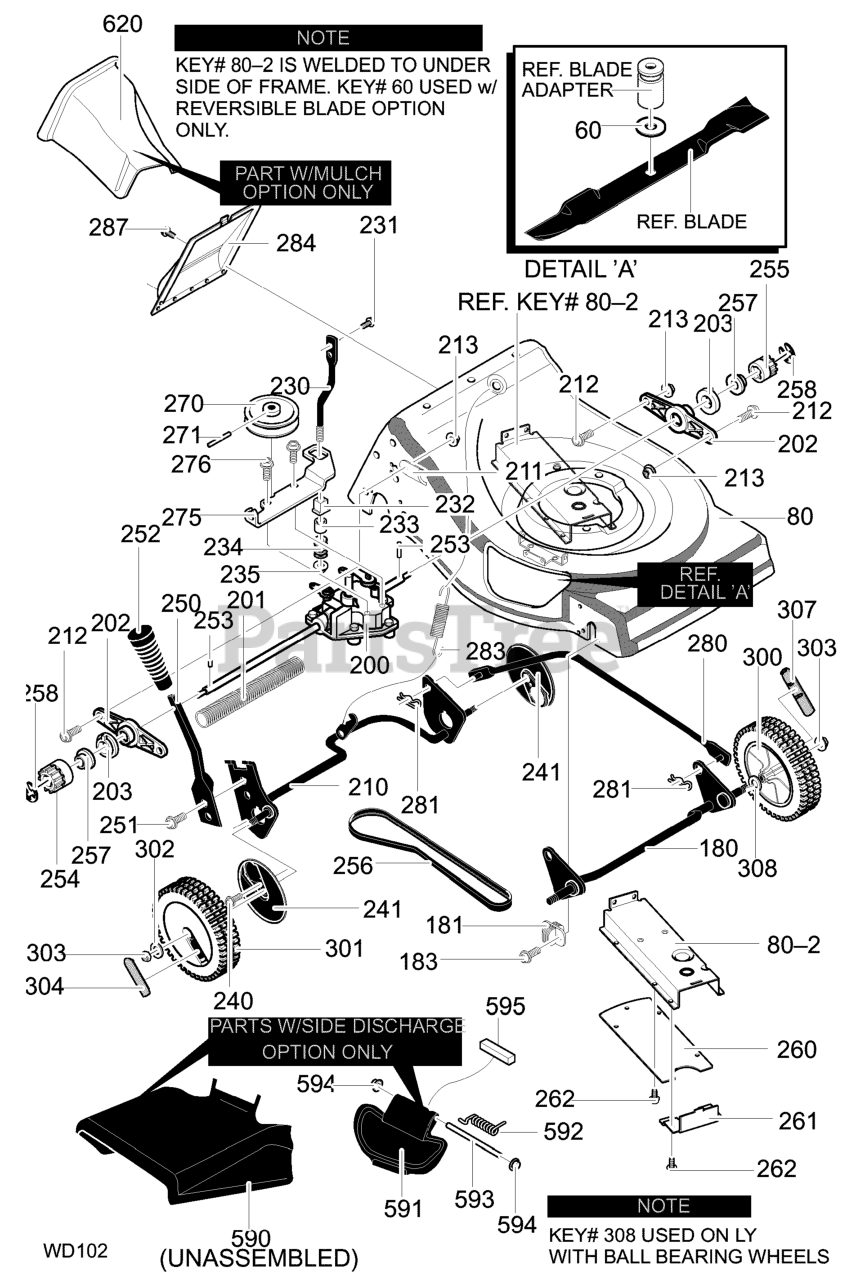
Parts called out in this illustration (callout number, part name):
80	ASSY, FRAME
80-2	BELT GUARD
180	CROSSBAR, FRONT
181	BUSHING
200	TRANSMISSION
201	SHIELD, AXLE
202	SUPPORT, AXLE
203	BEARING, LIFTER
210	ASSY, CROSSBAR
211	RETAINER, BEARING
212	SCREW, 5/16-18 x 0.75
213	NUT, 5/16-18
230	SUPPORT, SPRING
231	SCREW, 1/4-20X.63
232	BUSHING, SPRING
234	SPRING, COMP.
235	NUT, 5/16-18
240	SCREW, 1/4-14X.50
241	DUSTCOVER, 8"
250	LEVER, SPRING
252	KNOB, HEIGHT ADJ
253	DRIVE PIN
254	GEAR, PINION RT
255	GEAR, PINION LT
256	BELT, 2L V 15.75L
257	FLAT WASHER
258	RING, RET E
260	COVER, LWR BELT
261	COVER, FRT BELT
262	SCREW, 10-16X.50
270	PULLEY, 2L
271	PIN, SPRING
275	BRKT, TRANS. CABLE
276	SCREW, 1/4-20X.50
280	ASSY., LINK LIFTER
281	HAIR PIN
283	SPRING, EXTENSION
284	COVER, REAR
287	SCREW, 1.4-20X.63
300	TIRE & RIM
301	WHEEL, DRIVE
302	FLAT WASHER
303	NUT, 3/8-16
304	HUB CAP
307	HUB CAP
308	SPRING WASHER
590	DEFLECTOR, CHUTE
591	COVER, MULCH
592	SPRING, TORSION
593	ROD, PIVOT
594	CAP, PUSH ON
595	SEAL, FOAM
620	PLUG, MULCHER
